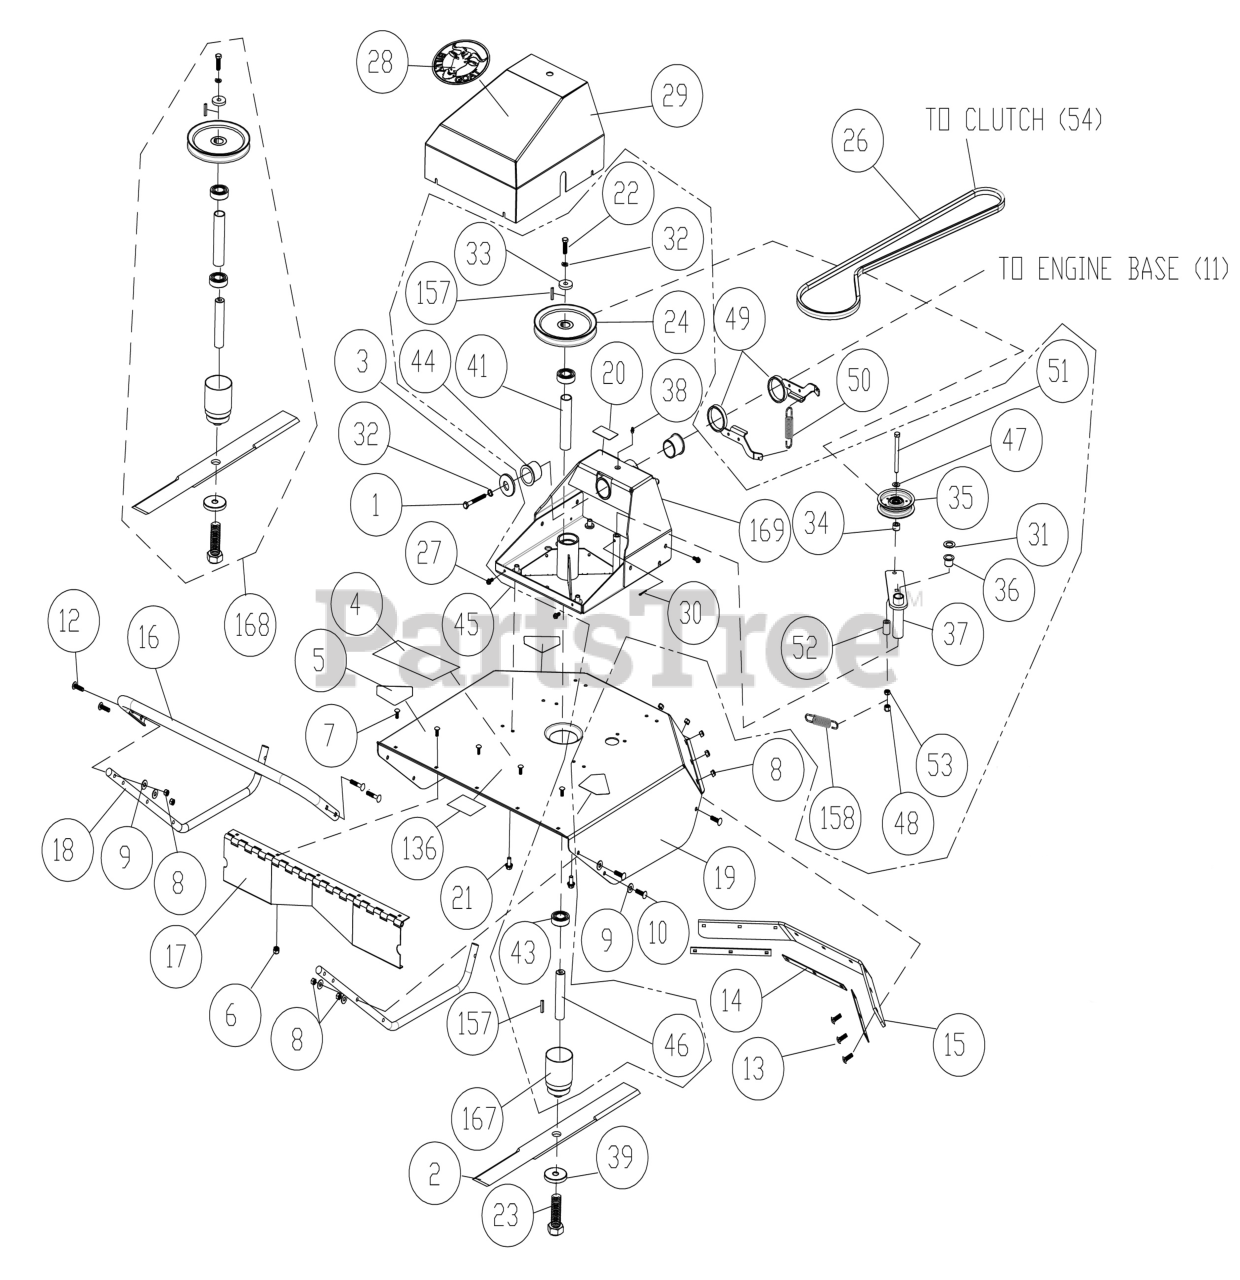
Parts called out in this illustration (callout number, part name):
1	SCREWCAP 3/8"-24 X 1" HCS GR 8
2	SEE: 501601
3	WASHER DECK RETAINING
4	LABEL BADGING BC26 HYDRO
5	LABEL WARNING OPEI
6	NUT LOCK 1/4"-20 HEX Z/P
7	BOLT CARRIAGE 1/4" X 3/4"
8	NUT LOCK 5/16"-18 HEX Z/P
9	WASHER 5/16" FLATWASHER Z/P
10	SCREWCAP 5/16"-18X1 1/2" HCS ZP
12	BOLT CARRIAGE 5/16"-18 X 1 3/4" ZP
13	BOLT CARRIAGE 5/16"-18 X 1" ZP
14	PLATE CLAMP SKIRTING BC26
15	DEFLECTOR RUBBER
16	BAR GUARD BC26
17	HINGE DEFLECTOR BC26
18	SKID BC26
19	DECK BC26 WA W/LABELS
20	LABEL DANGER
21	SER HEX WASHER 3/8" - 16
22	SCREWCAP 3/8"-16X1 1/4" HCS ZP
23	SCREWCAP 9/16-18 X 1 3/4" GR8 ZP
24	PULLEY 7" OD X 1.000 BORE
26	BELT 6972 POWERATED
27	SCREW SELF TAP 1/4"-20 X 5/8" HWH TYPE F
28	LABEL LOGO QB
29	COVER BELT DECK WA BC26 W/LABEL
30	PIN COTTER 1/8" X 1" Z/P
31	WASHER .765" ID X 1.25 OD X .06"
32	WASHER LOCK 3/8" S/T MED
33	WASHER 1.5 OD X .453 ID X .25 THK
34	TUBE PIVOT IDLER
35	PULLEY IDLER 4" OD X 3/8"
36	BUSHING PIVOT FRAME AE
37	ARM IDLER DECK WA BC
38	ZERK FITTING GREASE
39	WASHER BLADE BC26
41	SPACER SPINDLE BEARING BC26
43	BEARING 1.00" SEALED PRESS IN
44	BUSHING 1.500 ID X 1.5 LONG FLANGED
45	DECK MOUNT WA W/LABELS
46	SHAFT BLADE DRIVE BC26
47	WASHER 3/8"SAE 13/32"X13/16"X1/16"
48	NUT LOCK 3/8"-16 HEX
49	ARM RTN WA BC26
50	SPRING LIFT ASSIST
51	SCREWCAP 3/8"-16X3 3/4"ZP
52	BUSHING PIVOT LIFT
53	NUT LOCK 3/8-16 LT WT THIN ZP
136	LABEL DANGER FLYING DEBRIS
157	KEY 1/4" SQ X 0.75"
158	SPRING IDLER BC
167	ADAPTOR, BLADE WA BC26
168	BLADE PULLEY AND ADAPTER KIT SERVICE
169	BRACKET, DECK MOUNT WA W/LABEL
